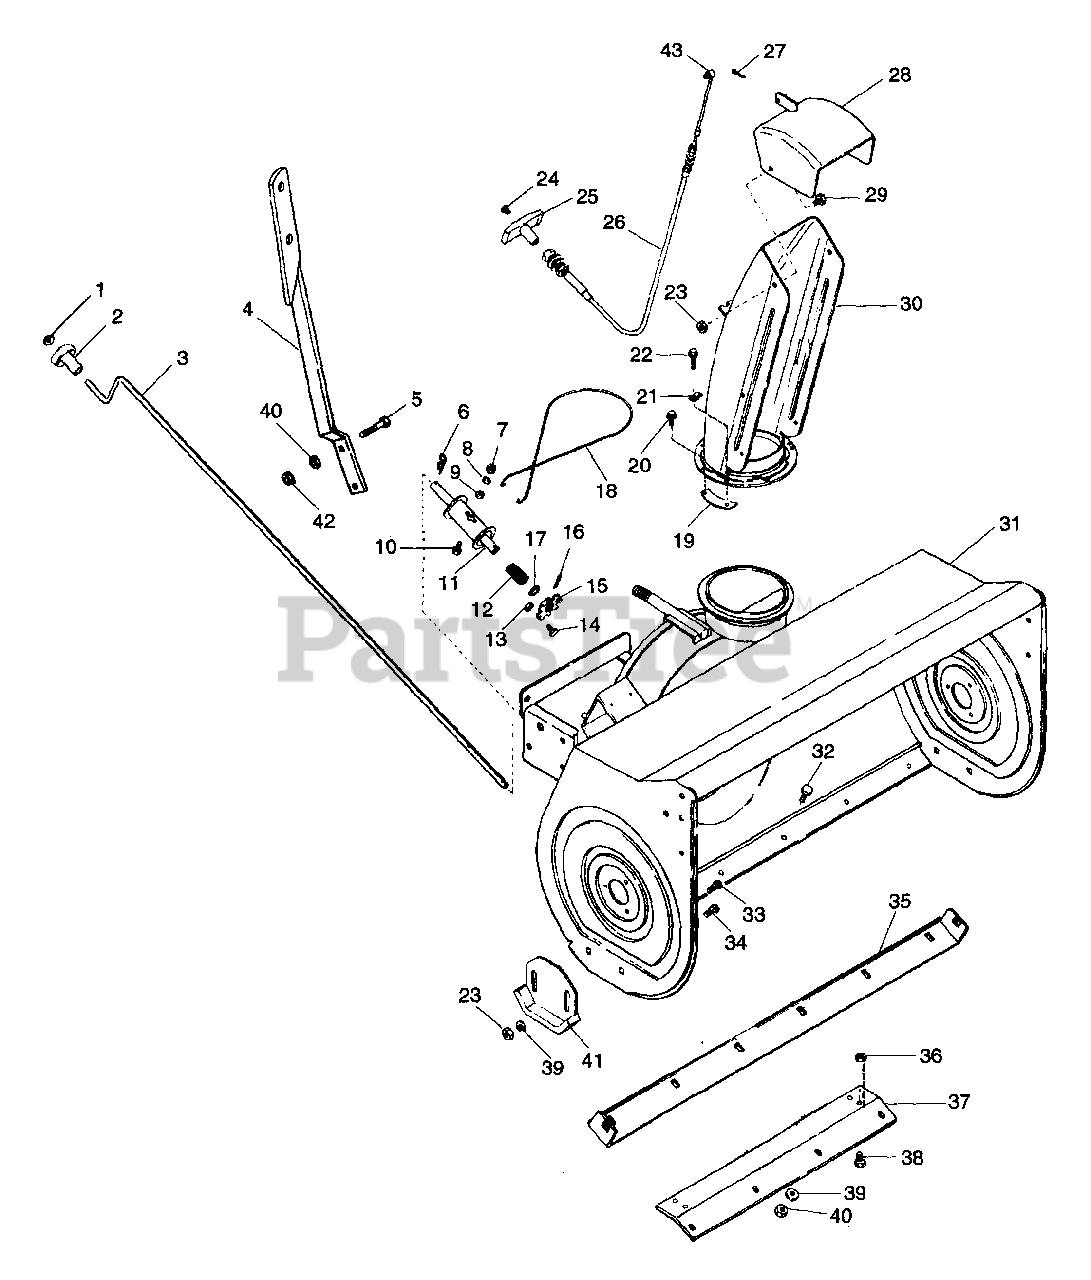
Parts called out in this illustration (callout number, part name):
1	NUT-LK-JAM-CTR .375-16 PL
3	CHUTE CONTROL CRANK
4	CHUTE CRANK SUPPORT
5	BLT-HEX .31-18X1.50 GR2 YWZC
6	PIN-HAIR INT .08X.38X1.42 YWZC
7	NUT-HEX .250-20 PL
8	WSHR-LK .313X.062
9	WSHR-FL-STL.281X.62X.065 PL
10	BLT-RDHDSQNK .25-20X.62 PL
11	SPOOL
12	SG-COMP .054X.75X1.6
13	NUT-LK DUAL FACE 10-24 PL
14	SCR-SKH 10-24X.38
15	DISC ASSEMBLY
16	PIN-ROLL .188X1.00
17	WSHR-FL-STL .640X1.005X.062 PL
19	CHUTE CLAMP
20	SCR-TAP 10-24X.484 HWH TR
21	CABLE CLAMP
22	SCR-TAP 10-24X.75 HWH PL TR
23	NUT-LK-CTR .375-16 GR A PL
24	SCR-MCH 8-32X.75 SLPAN PL
25	KNOB-BLACK
26	CONTROL CABLE
27	PIN-COTR .09X.75 PL
28	CHUTE DEFLECTOR
29	BLT-HEX .38-16X.75 PL GR2
30	DISCHARGE CHUTE
31	40 AUGER/16 IMPELLER HOUSING
32	BLT-RDHDSQNK .31-18X.75 SHT PL
33	BLT-RDHDSQNK .38-16X.75 SHT PL
34	BLT-RDHDSQSHNK .38-16X1.00 PL
35	SCRAPPER BLADE
36	NUT-LK TOP .375-16 GR C YWZC
37	SCRAPER BLADE BRACE
38	BLT-HEX .38-16X.75 PL GR5
39	WSHR-FL-STL .38X.875X.083 PL
40	NUT-LK .312-18 GR A PL
41	RUNNER-SKID SHOE
42	NUT-FLG. .312-18 PL
